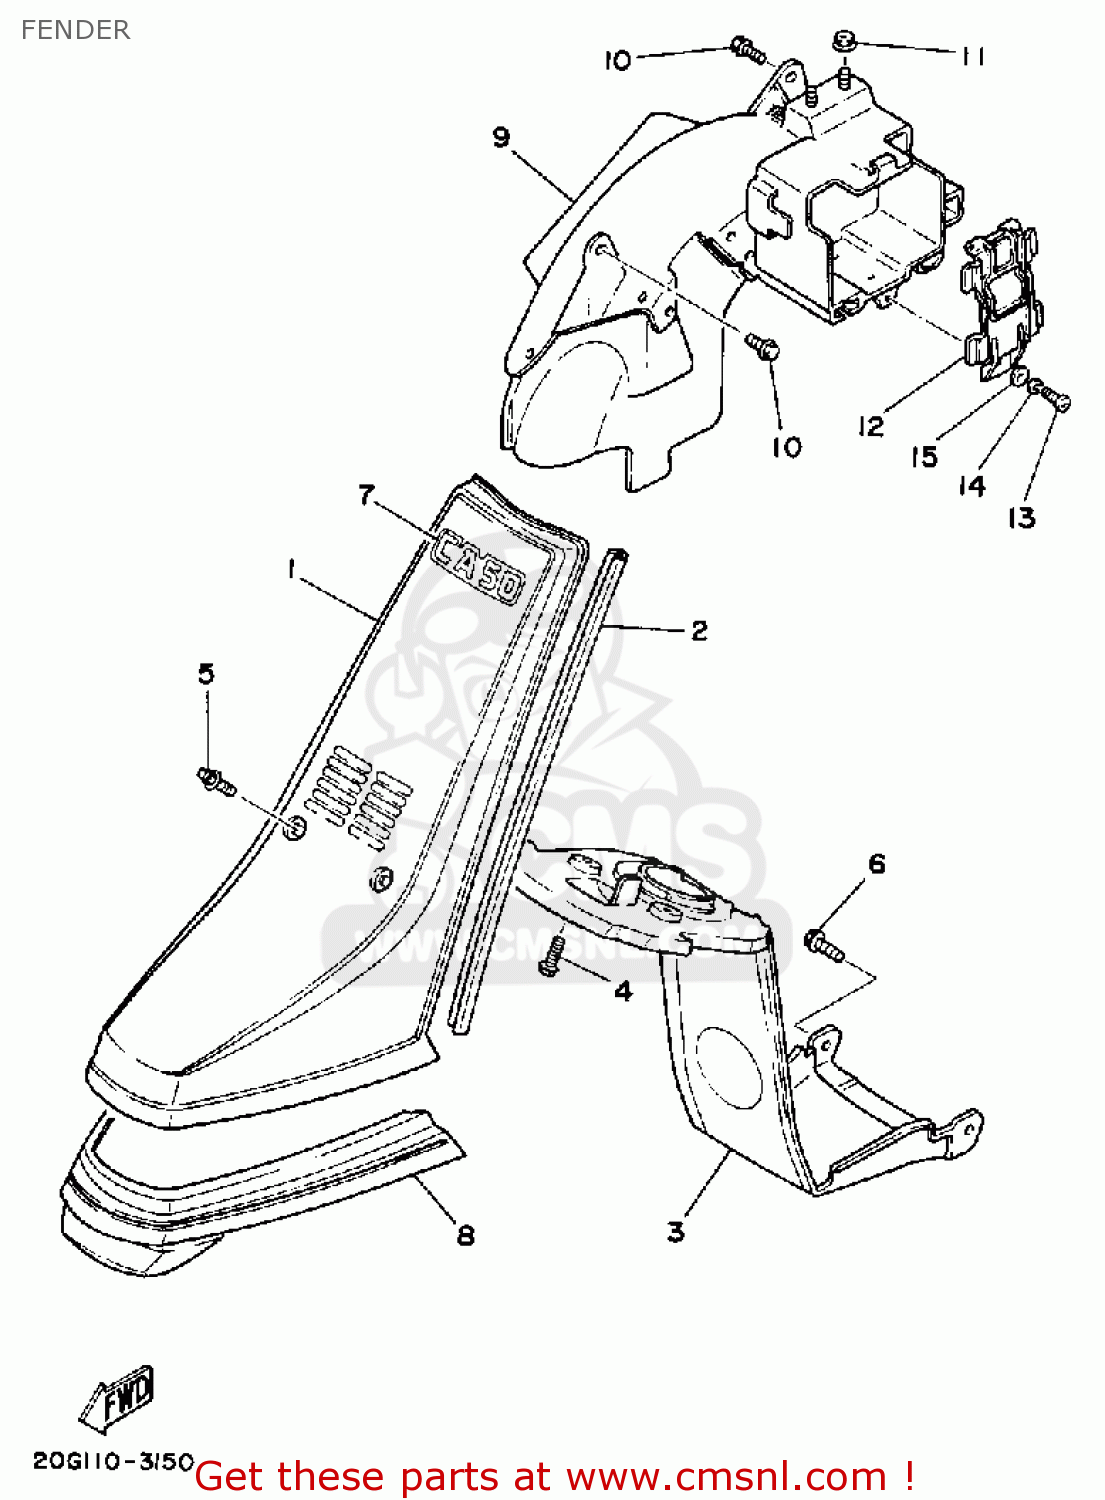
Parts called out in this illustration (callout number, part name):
1	FENDER, FRONT
2	MOLD, FENDER
3	FENDER, INNER
4	BOLT, HEXA W/W
5	BOLT H/H W/W (EU0)
6	BOLT, WITH WASHER (14T)
7	EMBLEM 1
8	MOLD, FENDER
9	MUD GUARD COMP.
10	BOLT, HEXA W/W
11	NUT, FLANGE(34M)
12	PLATE 1
13	SCREW, PAN HEAD (7H3)
14	YBS67-5 WASHER, SPRING
15	WASHER, PLATE 8067717800
